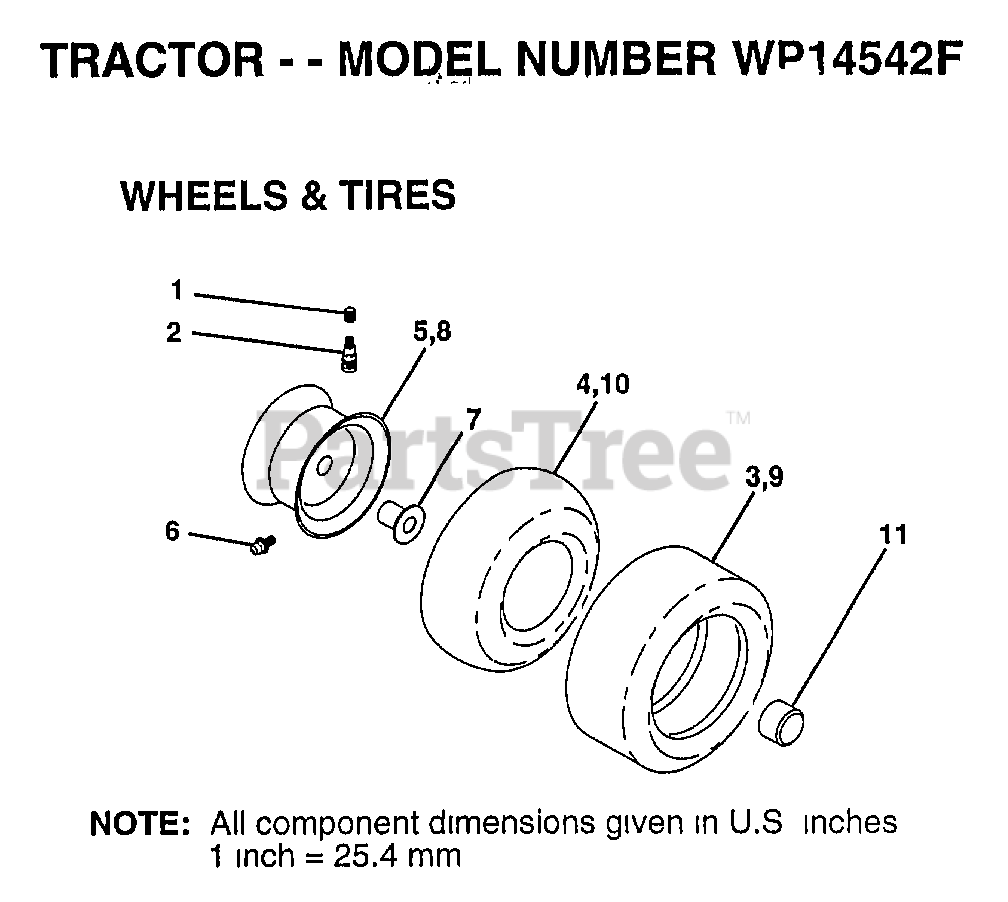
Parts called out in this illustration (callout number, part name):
1	VALVE CAP
2	VALVE STEM LT
4	TUBE.5.3/4.5/6
5	"RIM,FRT T"
6	FITTING LT
7	"FLANGE, BEARING"
8	"RIM 8"""
9	TIRE.20X8-8
10	TUBE.18X9.5-8
11	HUB CAP
